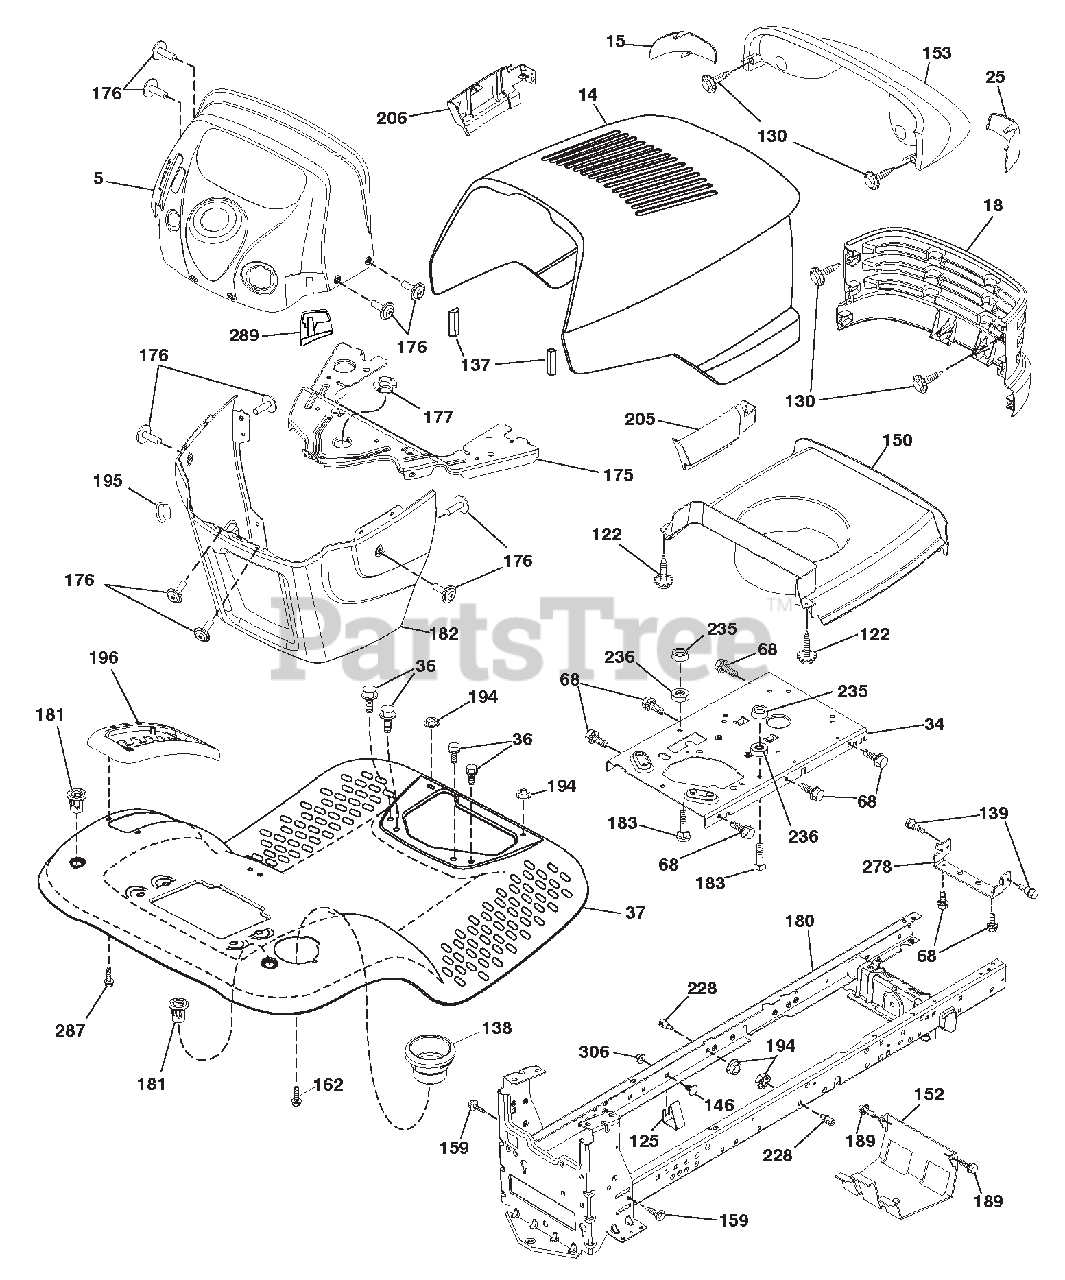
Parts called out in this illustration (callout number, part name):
5	DASH STEALTH ELE RECT 428 TEX
15	LENS ELITE ARIENS BLACK
18	GRILLE ELITE ARIENS BLACK
25	LENS ELITE HUSQ CLEAR RH
34	PLATE.ENGINE.WELDED.CHASSIS
36	SCREW.5/16-18X3/4.SMGML.TAP/R
37	FENDER TLT W/CPH W/FW 422
68	SCREW.THDROL.5/16-18 X 1/2TYTT
122	SCREW TO 32 X 5/8
125	CLIP.FUEL.LINE
137	BUMPER HOOD LARGE 1.75
138	CUPHOLDER TL TEX 428
139	BOLT SHOULDER 5/16-18
150	AIR DUCT ENGINE ELITE SV
152	SHIELD.BROWNING.W/TEX
153	ASM LIGHT BOX
159	SCREW.HEXWSH THDR3/8-16X3/4.BL
162	SCREW.HEX.WSH.HI-LO.1/4X1/2UNC
175	CROSSMEMBER LT
176	SCREW.#10-24X5/8.RND.QUDRX.GIM
177	BUSHING.STEERING.YT/GT
180	CHASS WLDMT TL 12 GA/2PC 18/22
181	BUSHING MNT FEND CRGO BLK TEX
182	DASH TOWER LT CCS
183	BOLT.FIN.HEX.5/16-18 UNC X1-1/
189	SCREW.5/16-18X3/4.SMGML.TAP/BL
194	Nut, Lock Hex Flange 5/16-18 u
195	PLUG HOLE DASH TOWER
196	CONSOLE ASM.DECKLFT.BL/RBT.TLT
205	SKIRT SIDE RH ELITE HUSQ 428
206	SKIRT SIDE LH ELITE 428
228	STUD.FASTNER.W/'D'ANTI-ROTATIO
235	SPACER.FENDER
236	NUT.CENTER LOCK.5/16-18 UNC
278	X-PIECE HOOD
287	SCREW.HEX.WASHEAD.1/4-20 X 3/8
289	PLUG CRUISE CONTORL
306	Nut, Hex, Flangelock 3/8-16
